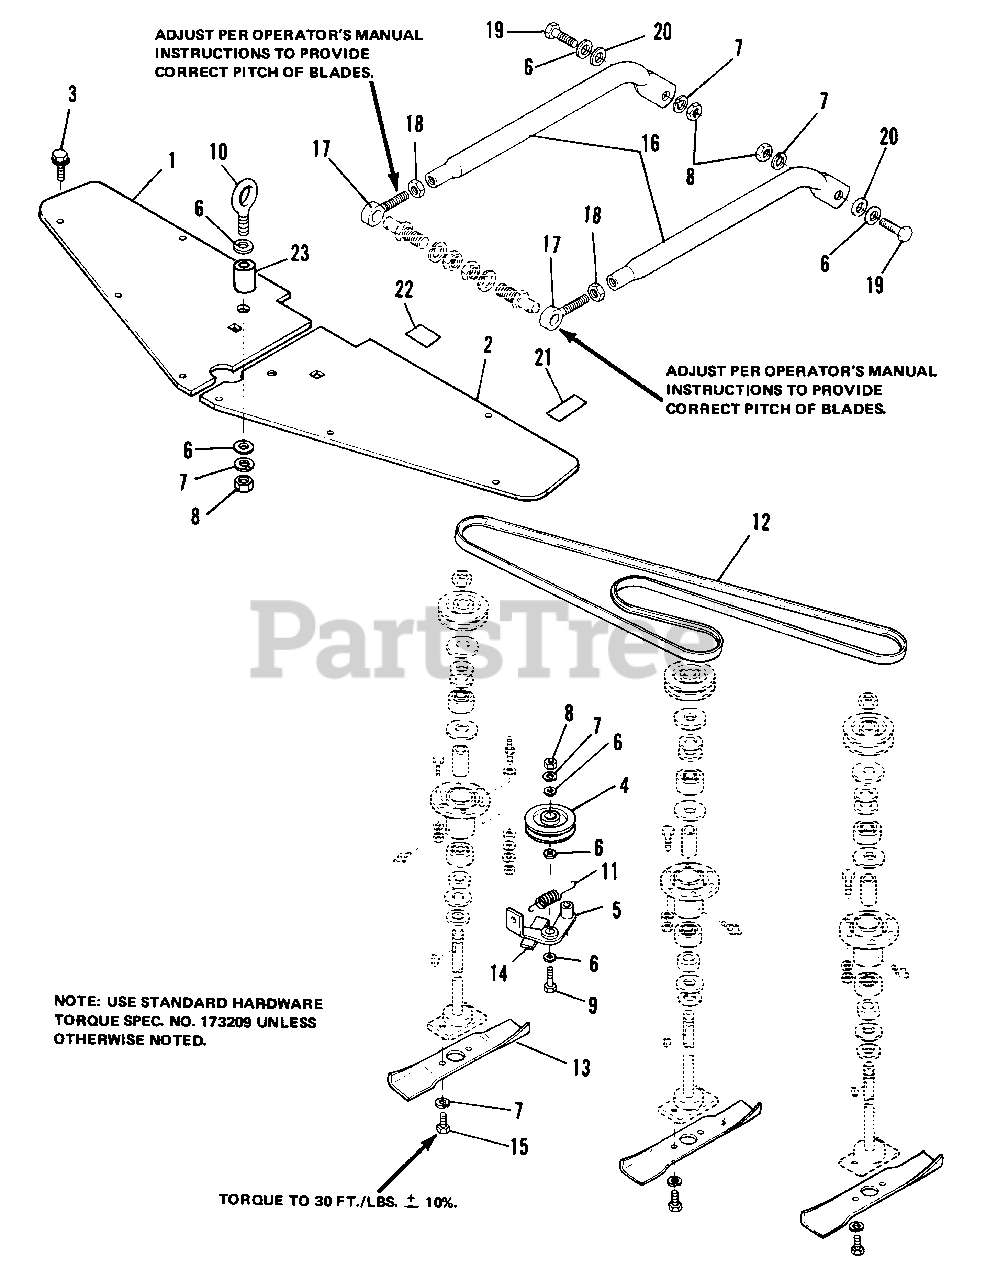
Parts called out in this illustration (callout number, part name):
1	COVER, R.H.
2	COVER, L.H.
3	SCREW, Hex Hd., Self-Tapping, 1/4-20 x 3/8
4	PULLEY, Idler
5	LEVER ASSY, Idler
6	WASHER, Plain, 5/16
7	LOCKWASHER, 3/8
8	NUT, Hex Full, 3/8-16
9	CAPSCREW, Hex Hd., 3/8-16 x 1-1/4
12	"V" BELT, Blade Drive
14	GASKET, Felt
15	CAPSCREW, Hex Hd, 3/8-16 x 5/8
16	ARM, Adjusting
18	NUT, Hex Jam, 1/2-20
19	CAPSCREW, Hex Hd., 3/8-16 x 1
21	FILM, Safety
22	FILM, Belt Installation
23	RACE, Inner
